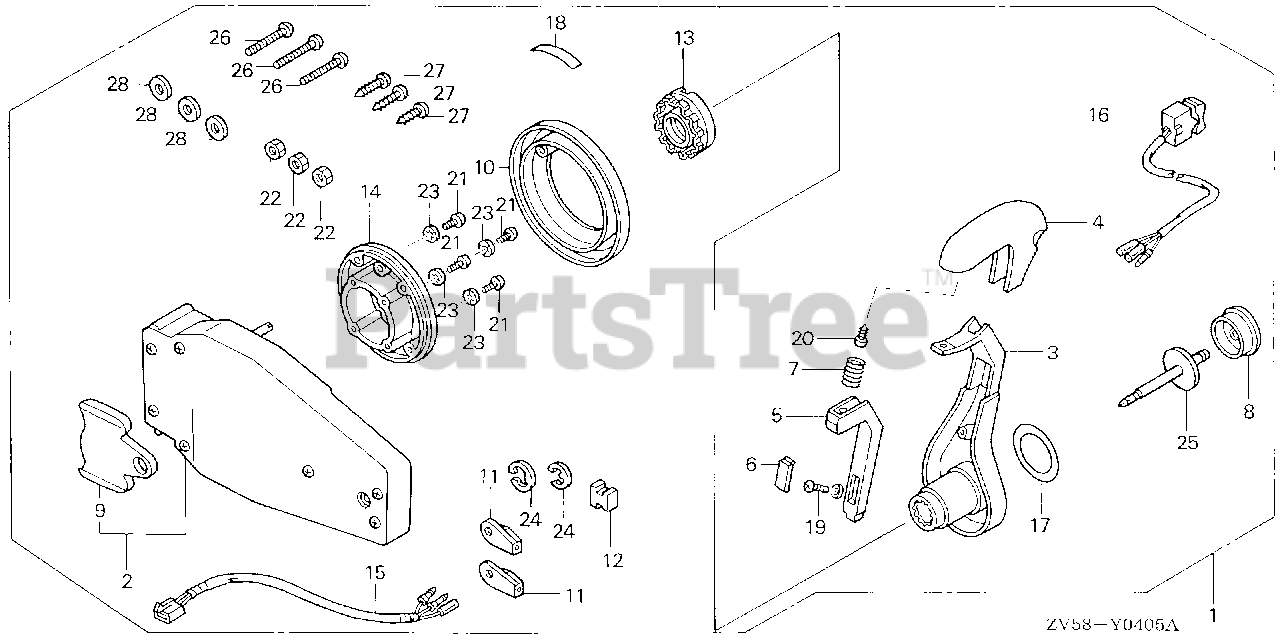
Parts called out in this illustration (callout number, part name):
1	BOX KIT, REMOTE CONTROL (FLUSH MOUNT)(L)
2	HOUSING ASSY., L. (INNER) (FLUSH MOUNT)
3	HANDLE, REMOTE CONTROL
4	COVER, GRIP
5	ARM, NEUTRAL LOCK
6	COVER, LOCK ARM
7	SPRING, NEUTRAL LOCK ARM
8	BUTTON, THROTTLE
9	PLATE, DWELL
10	COVER ASSY.
11	TERMINAL, CABLE
12	SPACER, CABLE CLAMP
13	HOLDER, NEUTRAL LOCK
14	BASE
15	SUB-HARNESS ASSY., POWER TRIM-TILT (C)
16	SWITCH ASSY., POWER TRIM-TILT (C)
17	MARK, HANDLE FLUSH MOUNT
18	MARK, FLUSH MOUNT
19	SCREW, PAN (5X16)
20	SCREW, TRUSS (4X12)
21	SCREW, PAN (5X30)
22	NUT, HEX. (6MM)
23	WASHER, LOCK (5MM)
24	E-RING (6MM)
25	SHAFT, THROTTLE BUTTON
26	SCREW, PAN (6X35)
27	SCREW, TAPPING (6X30)
28	WASHER, PLAIN (6MM)
